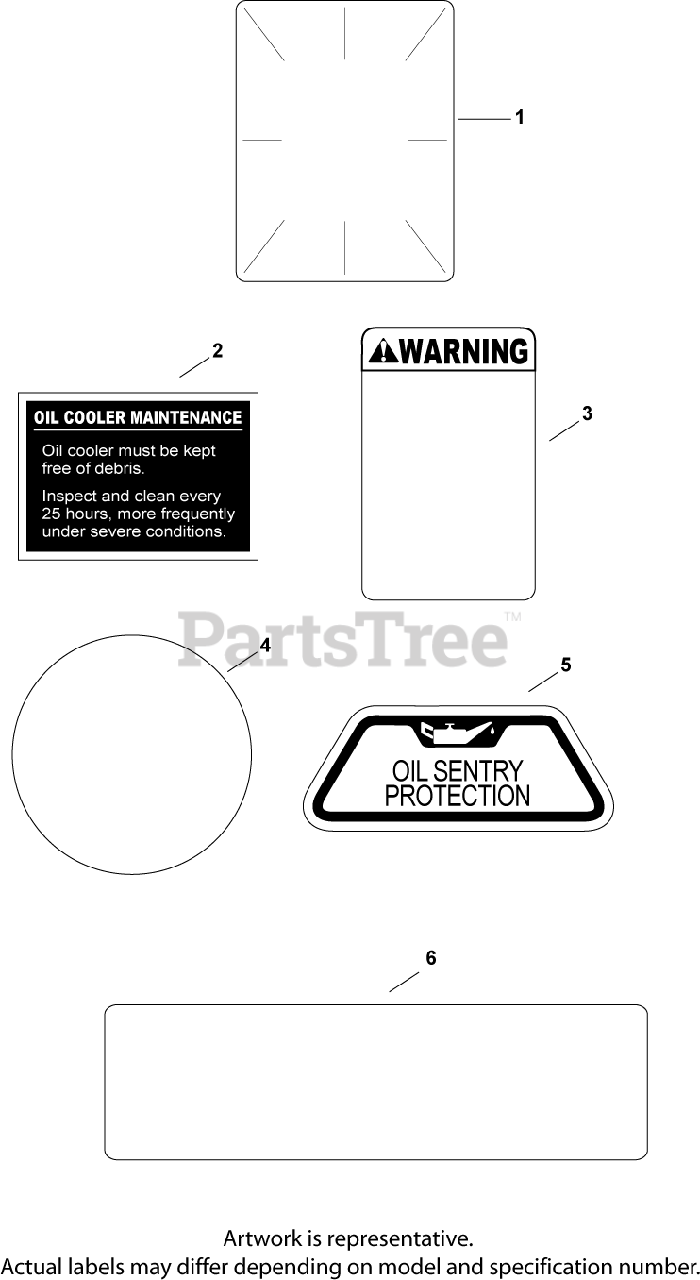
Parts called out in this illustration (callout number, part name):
1	DECAL, CLEAR LAMINATE USE 25 113 70-S
2	DECAL, OIL COOLER - (#DSC)
3	DECAL, CO WARNING
4	DECAL, GRASS SCREEN USE 24 113 499-S
5	DECAL, OIL SENTRY - (#DSC)
6	DECAL, COMMAND (GASEOUS) - DISCONTINUED
